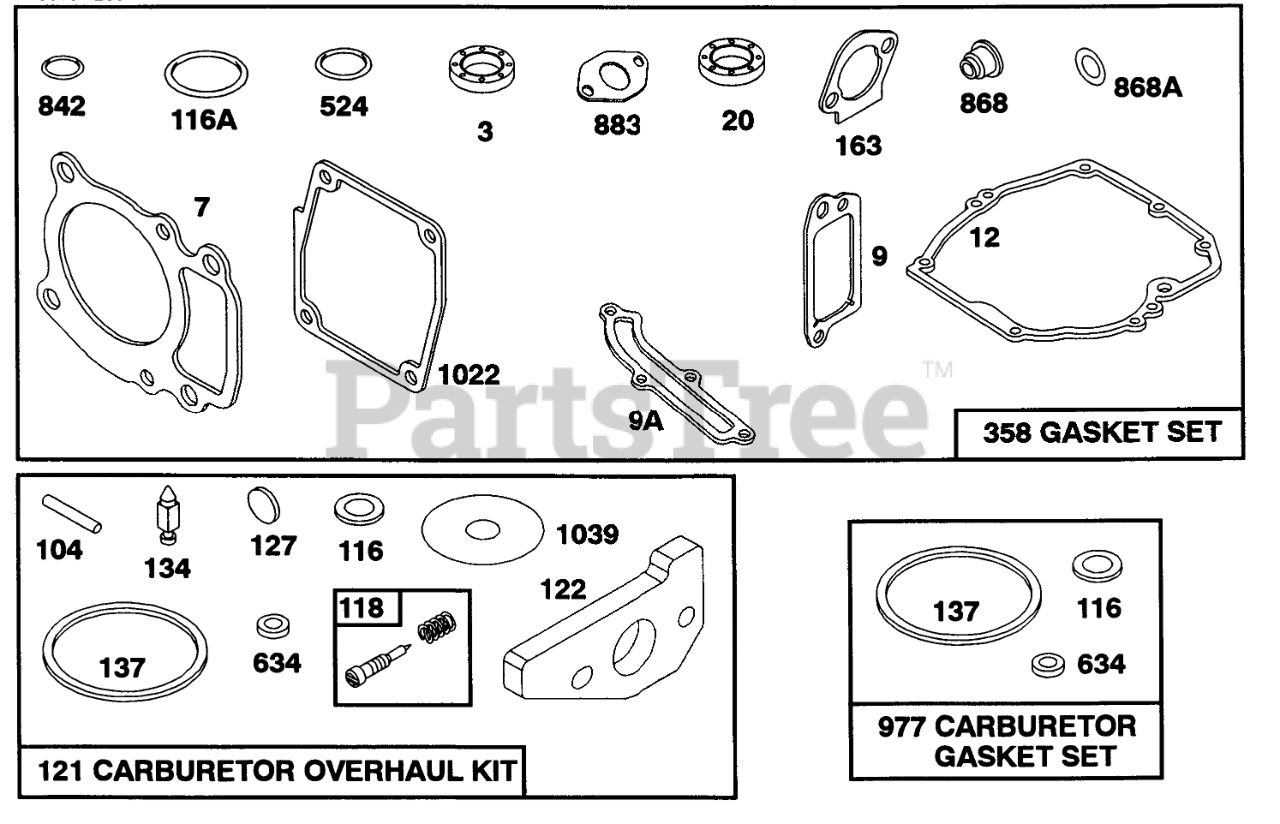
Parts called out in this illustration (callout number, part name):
3	SEAL - OIL
7	CYLINDER HEAD GASKET
9	BREATHER GASKET
9A	GASKET-BREATHER
12	ENGINE BASE GASKET
20	SEAL-OIL
104	FLOAT HINGE PIN
116	SEALING GASKET
116A	O RING SEAL
118	VALVE KIT - NEEDLE
121	CARBURATOR OVERHAUL KIT
122	ADAPTER ASSEMBLY
127	PLUG
134	Valve-Inlet (Includes Seat)
137	FLOAT BOWL GASKET
163	AIR CLEANER GASKET
358	GASKET SET
524	O-RING
634	SEAL WASHER
842	O-RING
868	SealAssy-Valve
868A	Seal-Valve
883	EXHAUST GASKET
977	CARBURATOR GASKET SET
1022	ROCKER COVER GASKET
1039	FLOAT LIMITER
